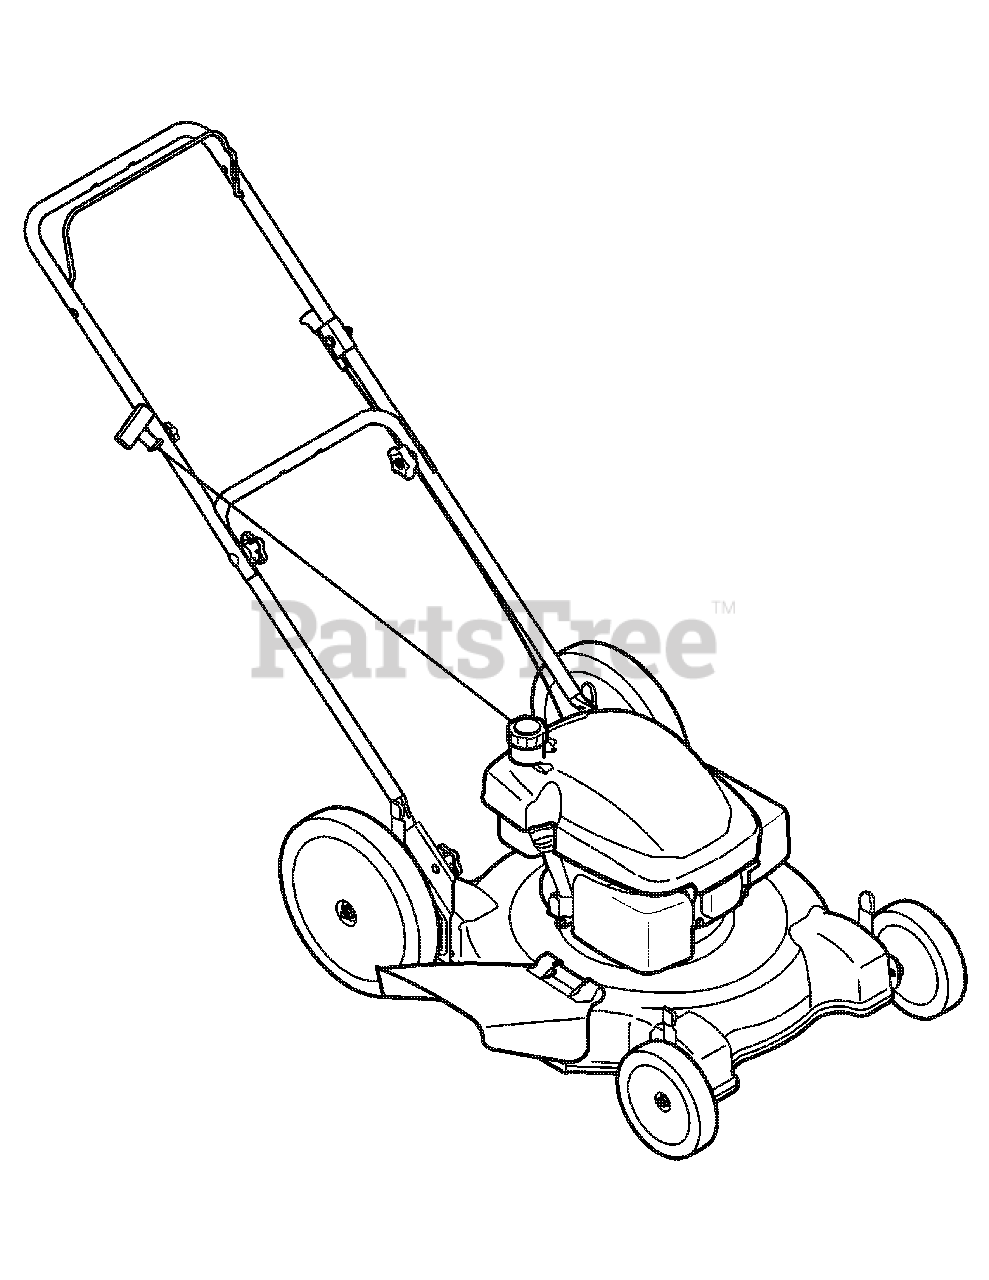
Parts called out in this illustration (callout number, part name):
NA	Pre-Filter
NA	Drive Belt
NA	Drive Cable
NA	Grass Bag
